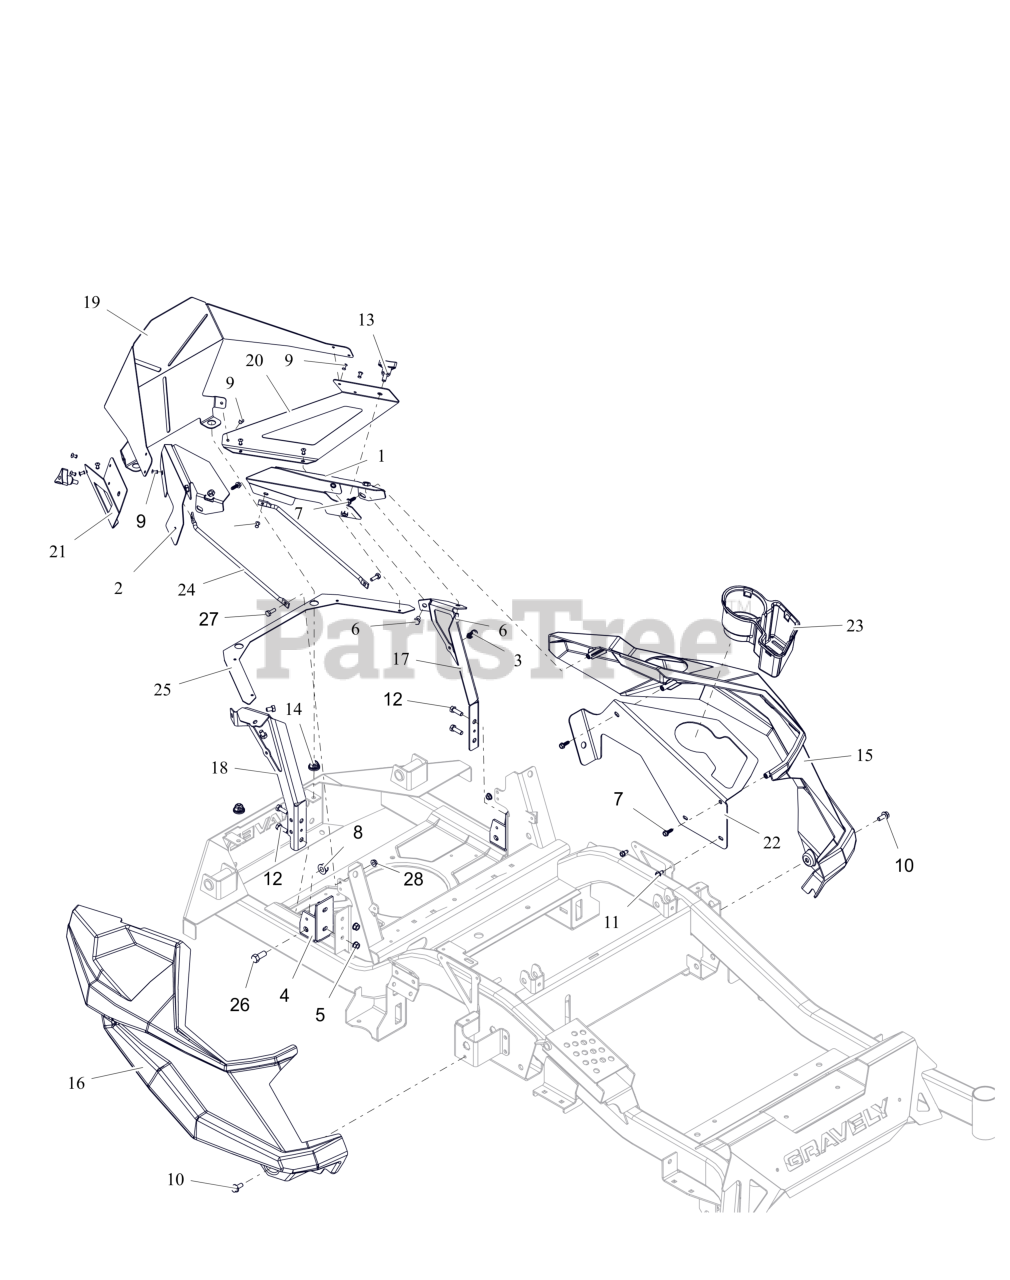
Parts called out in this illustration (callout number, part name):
1	PANEL, LH (RED)
2	PANEL, RH (RED)
3	CLIP, CABLE GUIDE
4	BRKT, ROPS SUPPORT
5	NUT,LK-CTR-FLG .31-18 GF ZCC
6	BLT, HEX .31-18X.50 GR5 ZCC
7	SCR, PLASTITE-HWH 0.25 X 0.75 ZC120
8	NUT,NYL-FLG .44-14 GF ZCC
9	RIVET, #66 STEEL POP PD BLACK
10	BLT, SERHFWH 0.312-18X0.75 GR5 ZCC
11	SCR-TAP .25-20X.50 HWH ZCC
12	BLT, HEX .31-18X1.00 G8 ZCC
13	KNOB,WING STUD 5/16-18 X .75
14	GROMMET, 10MM BOLLHOFF
15	FENDER, LH
16	FENDER, RH
17	BRKT, LH FENDER MTG (RED)
18	BRKT, RH FENDER MTG (RED)
19	WRAP, REAR (BLACK)
20	WRAP, REAR - LH (RED)
21	WRAP, REAR - RH (RED)
22	PANEL, HD CUPHOLDER (RED)
23	HOLDER, CUP
24	ROD, STIFFENER
25	STIFFENER, BACK WRAP (RED)
26	BLT, HEX 0.4375-14X1 GR5 ZCC
27	BLT, HEX .25-20X.75 G5 ZCC
28	NUT-LK-CTR-FLG .25-20 ZC120
